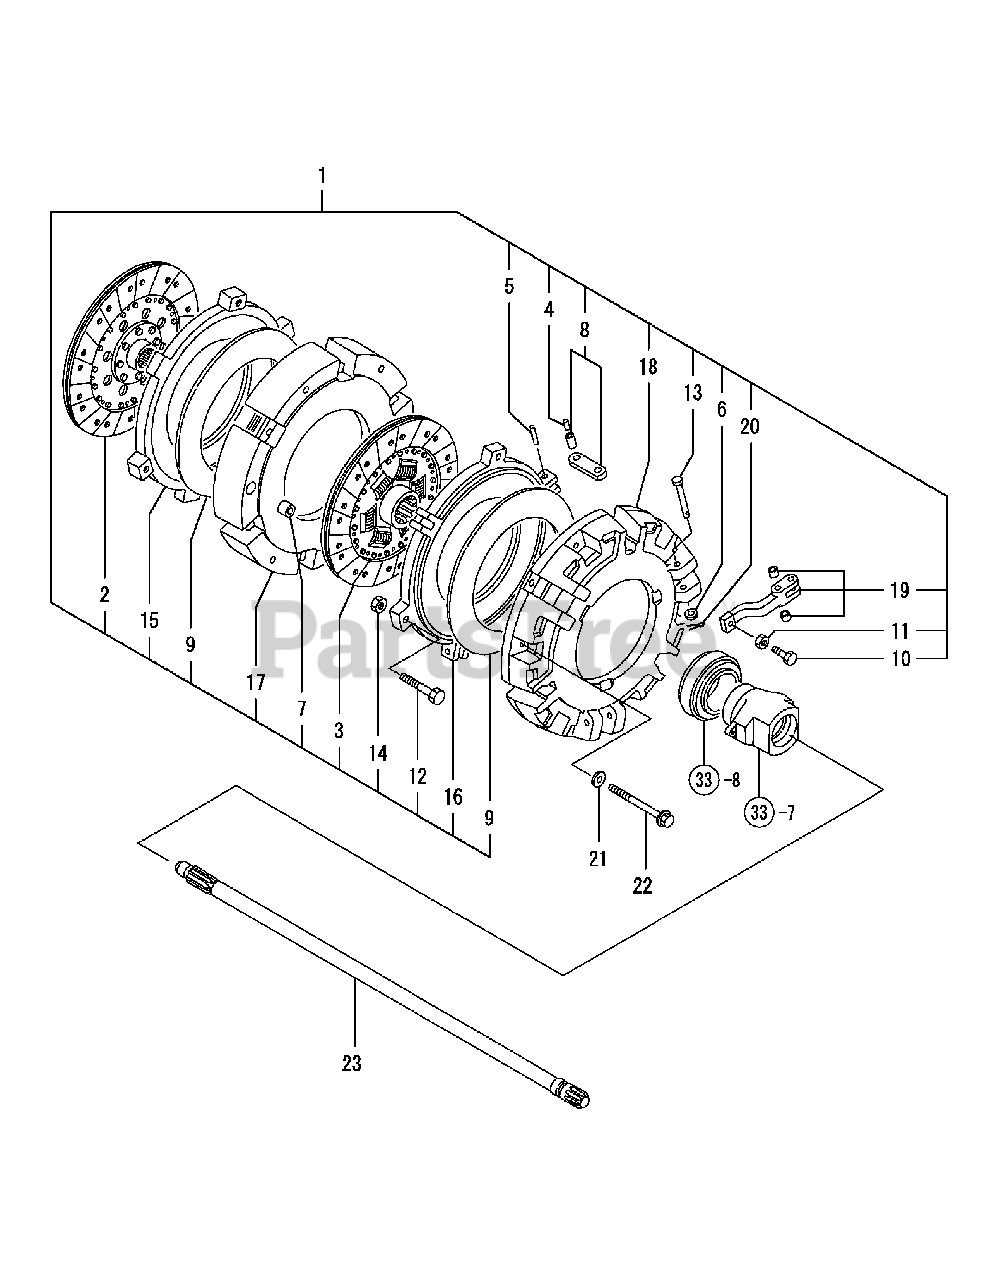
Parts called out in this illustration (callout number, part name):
1	DUAL CLUTCH ASSY
2	CLUTCH DISK, PTO
3	CLUTCH DISK, TRACTION
8	ROD ASSY, RELEASE
9	SPRING, DIAPHRAGM
15	PLATE A,PRESSURE
16	PLATE B,PRESSURE
17	COVER A,CLUTCH
18	COVER B,CLUTCH
20	COTTER PIN 1.6X15
21	WASHER 8, POLISHED
22	BOLT M 8X 80 PLATED
23	SHAFT,MAIN DRIVE,IN.
